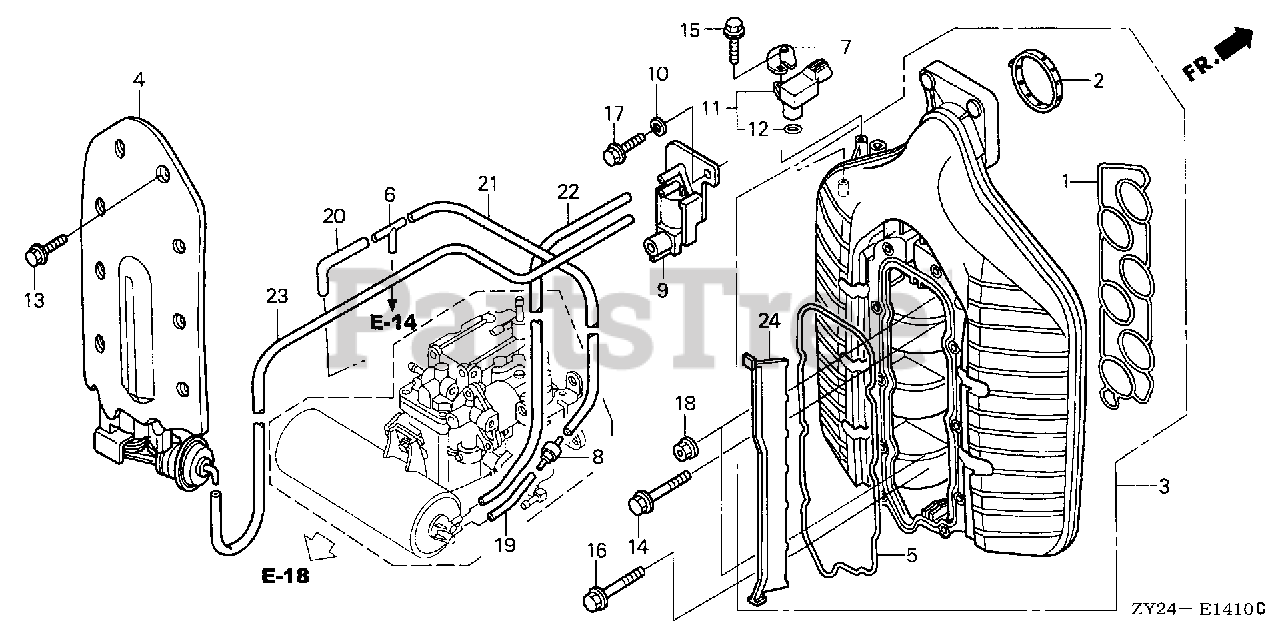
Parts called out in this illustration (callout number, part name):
1	GASKET, IN. MANIFOLD
2	GASKET, THROTTLE BODY
3	MANIFOLD, IN.
4	COVER, IN. MANIFOLD *NH8* (DARK GRAY)
5	GASKET, IN. MANIFOLD UP COVER
6	JOINT A, VACUUM TUBE
7	BRACKET, SENSOR WIRE
8	VALVE, CHECK
9	VALVE ASSY., AIR BYPASS
10	WASHER, CONICAL SPRING (5)
13	BOLT, FLANGE (6X22)
14	BOLT, FLANGE (8X50)
16	BOLT, FLANGE (6X32)
17	BOLT, FLANGE (5X10)
18	NUT, FLANGE (8MM)
19	BULK HOSE, FUEL (3.5X3000) (3.5X40)
20	BULK HOSE, FUEL (3.5X3000) (3.5X130)
21	BULK HOSE, FUEL (3.5X3000) (3.5X540)
22	BULK HOSE, FUEL (3.5X3000) (3.5X590)
23	BULK HOSE, FUEL (3.5X3000) (3.5X600)
24	PLATE, IN. MANIFOLD CENTER
